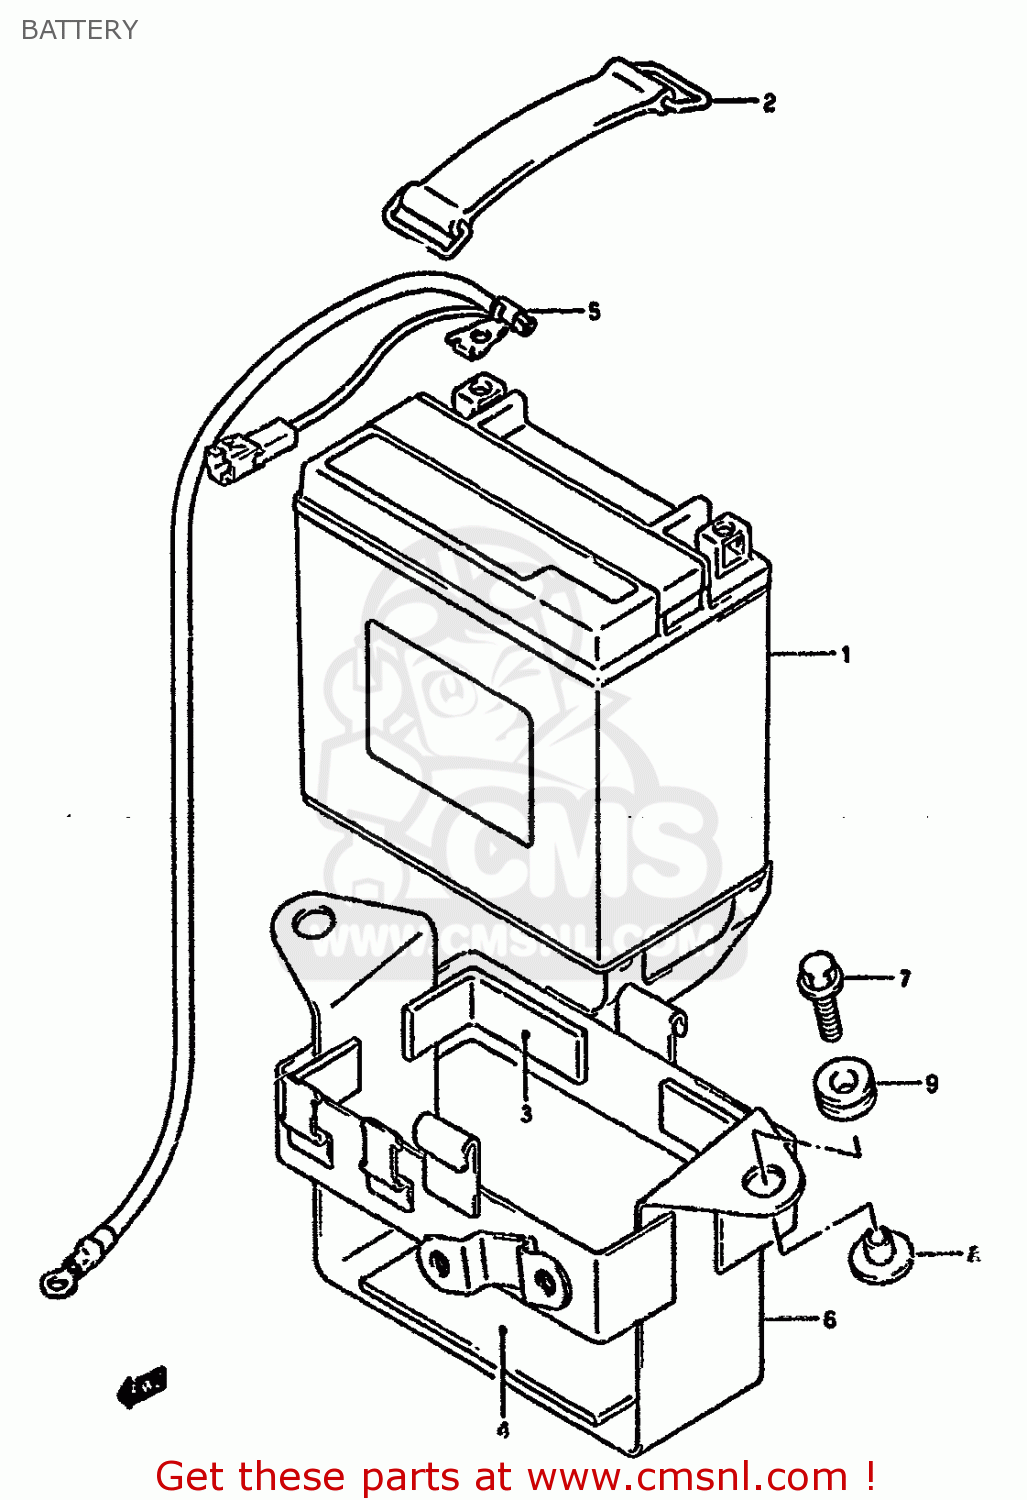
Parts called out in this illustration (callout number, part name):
1	BATTERY ASSY (12V) YTX14-BS
2	BAND
3	PROTECTOR(170X95X3.0)
4	PROTECTOR(170X95X3.0)
5	WIRE,BATTERY MINUS LEAD
6	HOLDER,BATTERY
7	BOLT
8	PLATE,BATTERY HOLDER
9	CUSHION
